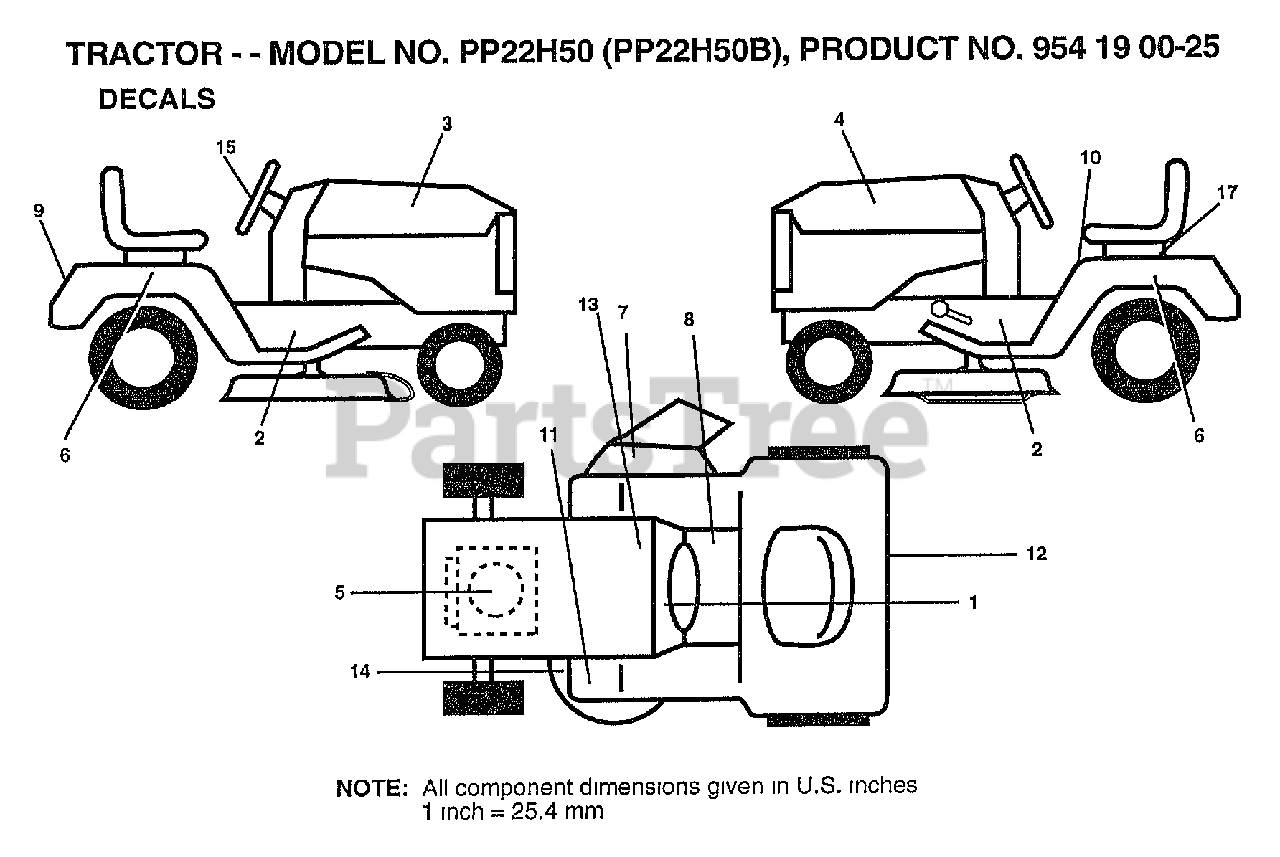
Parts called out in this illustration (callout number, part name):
1	"DECAL-INST,OPER"
2	"DECAL.CHASSIS.50"""
3	DECAL.HOOD.RH
4	DECAL.HOOD.LH
5	DECAL/D-BAR CTRL MVT HYD YT/GT
6	DECAL.FENDR.AUTO
7	"DECAL, WARNING"
8	DECAL BRAK PARK
9	DECAL.FENDER.BELT.GUARD
10	DECAL.CAUT.ENG/FR
11	DECAL T
12	DECAL D-BAR CNTRL
13	DECAL.BATRY.3-3908
15	DECAL INS STRG WH
17	RETAINER-SPRING
